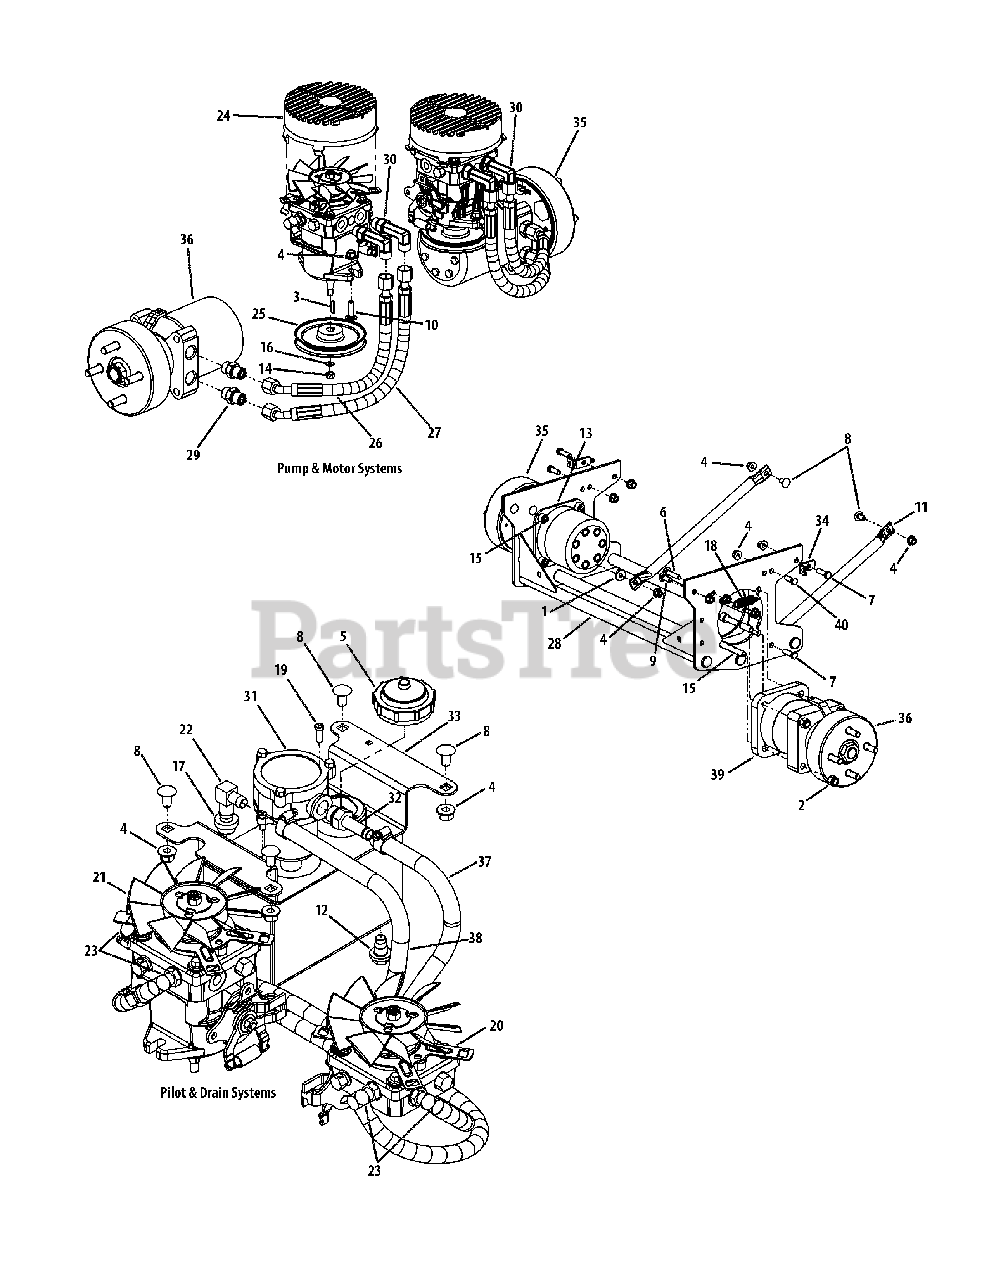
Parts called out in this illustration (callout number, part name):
1	Idler Washer
2	Washer lock 3/8 zinc
3	Key, 3/16" x 7/8"
4	Flange Lock Hex Nut, 3/8-16
5	Cap, Hydro Oil Tank
6	Hex Carriage Screw, 3/8-16, 1.75
6	Hex Carriage Screw, 3/8-16, 5.00 (M72)
7	Hex Cap Screw, 3/8 -16 x 1.25
8	Carriage Bolt, 3/8-16 x .75 LG.
9	Carriage Bolt, 3/8-16 x 1
10	Carriage Screw, 3/8-16 x 1.25
13	Hydro Wheel Motor Backup Plate
14	Hex Nut, 3/8-24
15	Socket Head Cap Screw, 1/2-13; 3-1/2
15	Socket Head Screw, 1/2-13; 6-1/2 (M72)
16	Flat Washer, .469 ID X .875 OD X .105
17	Grommet Fitting, .54 ID x .78 OD
18	Spring Extension, .740 OD x 2.656
19	Head Cap Screw, 1/4-20 x 0.75
20	Hydro Pump, BDP-12, RH
20	Kit, Fan
21	Hydro Pump, BDP-12, LH
21	Kit, Fan
22	Fitting Elbow Spur, 5/8 x 1/2
23	Fitting Elbow, 9/16 x 1/2
24	Fan Pump Shroud
25	Hydro Pump Pulley
26	Short Pressure Hose Assembly
26	Short Pressure Hose Assembly (M72)
27	Long Pressure Hose Assembly
27	Long Pressure Hose Assembly (M72)
29	Adaptor Fitting, 8 x 10
30	Adaptor, 8 x 8
31	Hydraulic In-Tank Filter
32	Replacement Filter
33	Fitting, 3/4 ORB x 1/2 Tube
34	Hydraulic Tank Assembly
35	Rear Cable Mounting Bracket
35	Rear Cable Mounting Bracket (M72)
36	Hydro Motor, LH Assembly
37	Hydro Motor, RH Assembly
37	Hose Assembly, Pilot
37	Tee Fitting, 1/2
37	Hose Clamp, 1/2
37	Fuel Hose, .50 ID x .75 OD
38	Hose Assembly, Drain
38	Tee Fitting, 1/2
38	Hose Clamp, 1/2
38	Fuel Hose, .50 ID x .75 OD
39	Spacer, Hydro, Wheel Motor
40	Hex Cap Screw, 3/8-16 x 1.00
41	Hex Cap Screw, 3/8-16 x 4.50 (M72)
